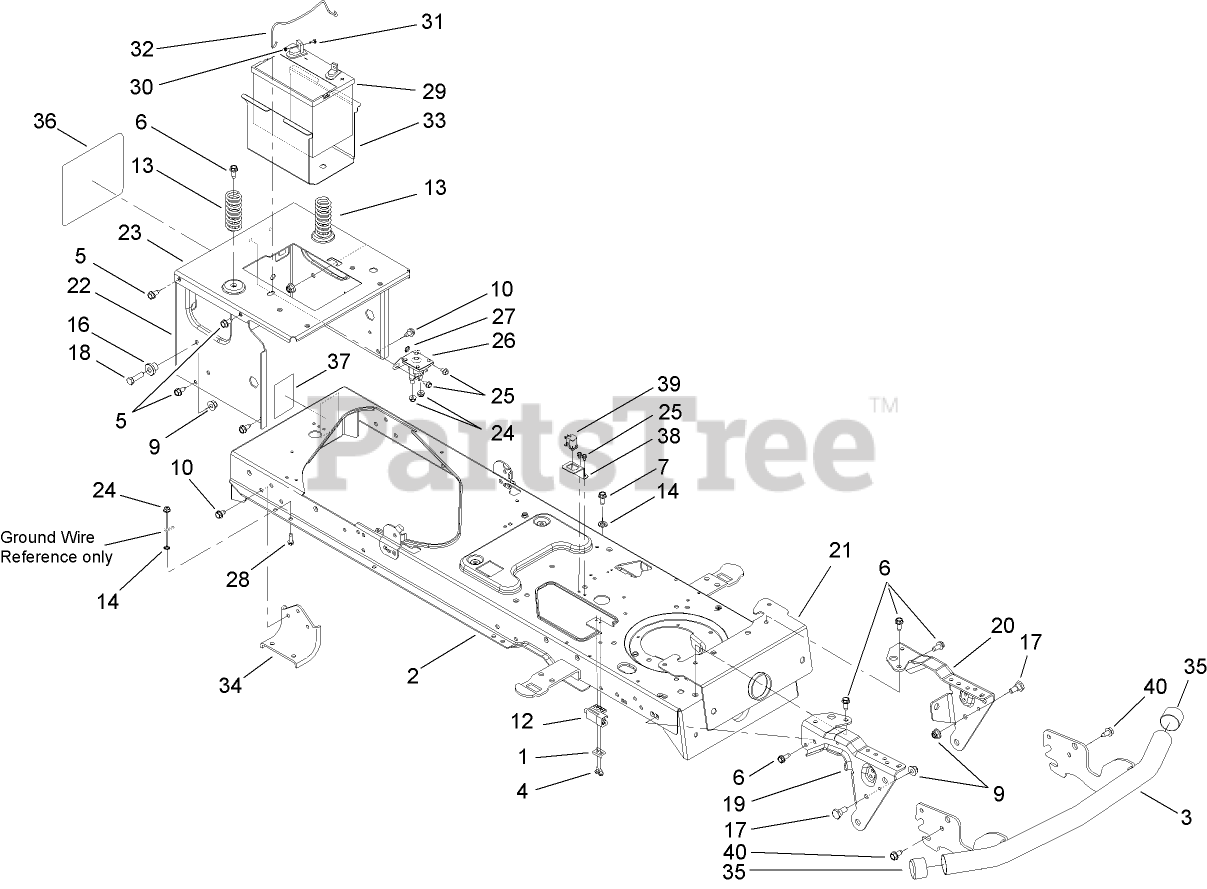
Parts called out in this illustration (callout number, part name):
1	PLATE-SWITCH
2	LOWER FRAME ASM
3	BUMPER ASM
4	SCREW-TAP
5	SCREW-HWH
6	SCREW-HWH
7	SCREW-HWH
9	NUT-LOCK, FLANGE
10	SCREW-TAP
12	SWITCH-INTERLOCK
13	SPRING-COMPRESSION
14	WASHER-LOCK, EXTERNAL
16	SPACER-SHOULDER
17	BOLT-SHOULDER
18	SCREW-HH
19	BRACKET-PIVOT, SUPPORT
20	BRACKET-PIVOT, SUPPORT
21	BRACKET-PIVOT, BAR
23	BRACKET-FRAME, SEAT
24	NUT-LOCK, FLANGE
25	SCREW-HWHTF
26	SOLENOID-12V, 2 POST 1 TAB
27	WASHER-LOCK, EXTERNAL
28	SCREW-TAP
29	BATTERY-245, CCA,DRY (FLAT TOP)
30	NUT-SEMS
31	BOLT-CARRIAGE
32	ROD-HOLDDOWN, BATTERY
35	CAP-HUB
36	DECAL-TORO
37	DECAL-BYPASS
38	BRACKET-SWITCH, PARKING BRAKE
39	SWITCH-MOUNT, SNAP
40	SCREW-HH, TAP
